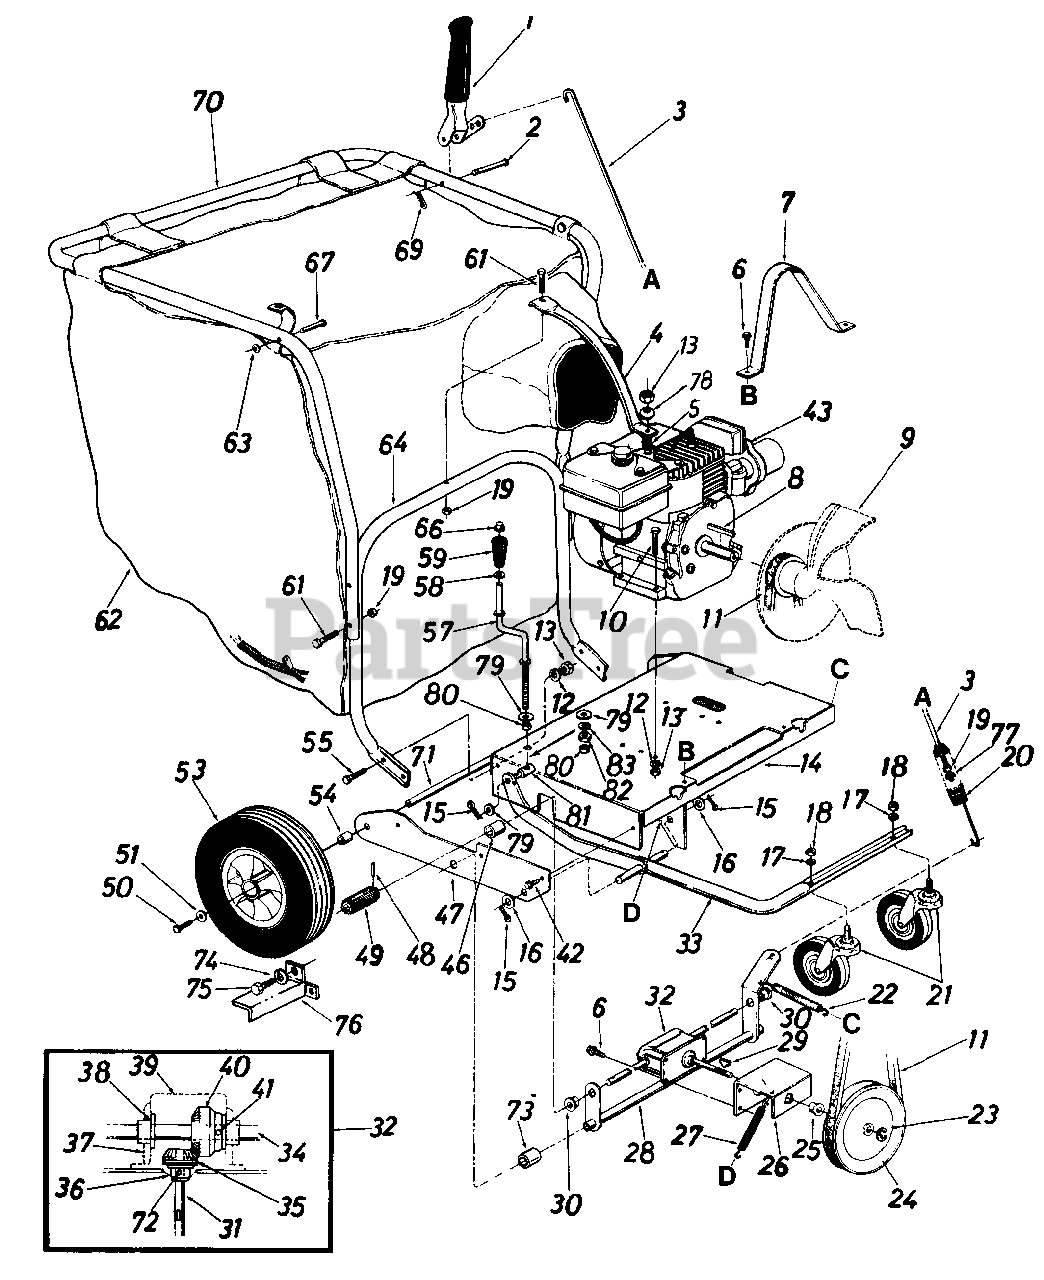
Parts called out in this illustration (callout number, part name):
3	Clutch Rod 32" Lg.
4	Handle Brace
5	Part of Engine
6	Hex Wash. Hd. AB-Tap Scr. 1/4" x .62" Lg.
11	"V"-Belt
12	L-Wash. 5/16" I.D.
13	Hex Nut 5/16-18 Thd.
16	Fl-Wash .63" I.D. x 1.25" O.D.
17	L-Wash. 1/2" I.D.
18	Hex Nut 1/2-13 Thd.
19	Hex Cent. L-Nut 1/4-20 Thd.
20	Extension Spring .78" O.D. x .75" Lg.
21	Swivel Caster Wheel 5" Dia. x 1.25"
22	Extension Spring .38" O.D. x 7.50" Lg.
23	Snap "E"-Ring .50" Dia. Shaft
24	"V"-Pulley 5/8" x 6.50" O.D.
25	Flange Bearing.502" I.D.
28	Clutch Bracket Ass'y.
29	#2 Woodruff Key 3/32" Dia. x .81" Lg.
30	Hex Flange Bearing Bronze .625" I.D.
31	Pinion Shaft .50" Dia. x 5"
32	Gear Box Ass'y. Comp.
35	Bevel Gear .50" I.D. x 14 Teeth
36	Flange Bearing .503" I.D.
37	Gear Box
38	Flange Bearing .630" I.D.
39	Gear Box Cover
40	Bevel Gear .62" I.D. x 28 Teeth
41	Spring Pin Spiral 3/16" Dia. x 1.25" Lg.
42	Hex Wash. Hd. AB-Tap Scr. 5/16" x .75" Lg.
43	Engine
46	Spacer .63" I.D. x .88" O.D. x .56" Lg.
49	Drive Pinion
50	Hex Locking Bolt 5/16-24 x .62" Lg.
51	Fl-Wash .34" I.D. x .87" O.D.
53	Wheel Ass'y. Comp. 12" x 3"
54	Spacer .63" I.D. x 1.0" 0.D. x .94" Lg.
55	Hex Bolt 5/16-18 x .75" Lg.
57	Height Adjustment Crank
58	Fl-Wash .385" I.D. x .62" O.D.
59	Crank Knob
61	Hex Bolt 1/4-20 x 1.75" Lg.
62	Vacuum Bag - Felt
63	Push Speed Nut .25" Dia. Stud
67	Stud Pin .250" Dia. x 1.75"
69	Internal Cotter Pin 3/8" Dia.
70	Upper Handle
71	Rear Axle
72	Spring Roll Pin 5/32" Dia. x 1.12
73	Spacer .82" I.D. x 1.0" Q.D. x .305 Lg.
74	L-Wash .265" I.D.
75	Hex Self-Tap Scr. 1/4" x 3/8" Lg.
78	Belleville Washer
79	Fl-Wash .35" I.D. x .87" O.D.
80	Spacer .38" I.D. x .50" 0.D. x .18" Lg.
81	Ferrule 3/8-8 x .38" Dia.
82	Hex Nut 3/8-8 Thd.
83	L-Wash. 3/8" I.D.
14530-0498	PLATE-SIDE-RH - OLD CUB YELLOW (0498)
14530-0499	PLATE-SIDE-RH - CUB BEIGE (0499)
14530-0637	PLATE-SIDE-RH - POWDER BLACK (0637)
14530-0638	PLATE-SIDE-RH - MTD/TROY-BILT RED (0638)
16273-0498	Double Caster Arm Assembly, Black - OLD CUB YELLOW (0498)
16273-0637	Double Caster Arm Assembly, Black - POWDER BLACK (0637)
16273-0638	Double Caster Arm Assembly, Black - MTD/TROY-BILT RED (0638)
16273-0648	Double Caster Arm Assembly, Black - TECH GRAY (0648)
16273-0662	Double Caster Arm Assembly, Black - OYSTER GRAY (0662)
16273-0674	Double Caster Arm Assembly, Black - YARDMAN YELLOW (0674)
16273-0691	Double Caster Arm Assembly, Black - BLACK JACK (0691)
16273-0709	Double Caster Arm Assembly, Black - MASTERCRAFT GREEN (0709)
